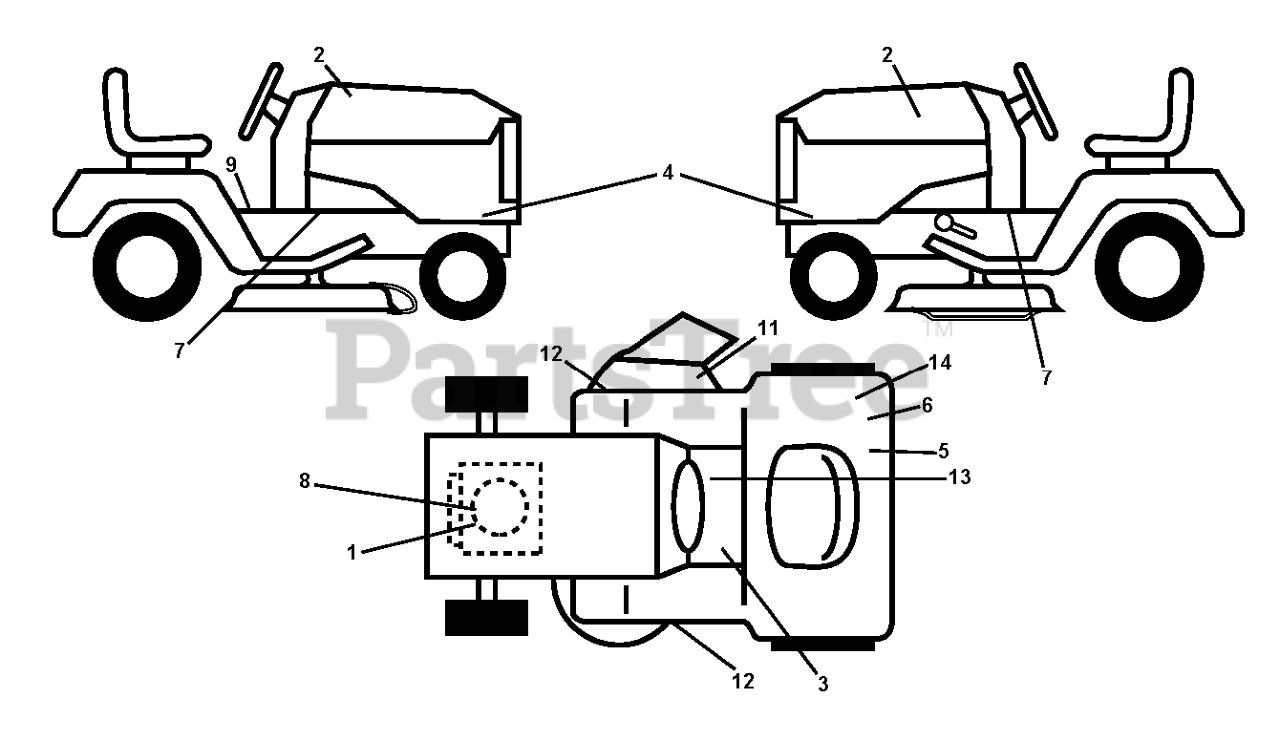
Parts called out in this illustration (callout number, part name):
1	DECAL
2	DECAL.HOOD.LOGO.ORANGE.HUSQVAR
3	DECAL
5	DECAL
6	DECAL
9	DECAL BTRY SYMBOLS
10	LABEL
11	DECAL.WARN.DFLECT/CTFINGR.SRD
12	Decal, Mower V-Belt Schematic
13	DECAL PARK BRAKE
14	DECAL 80 DBA
